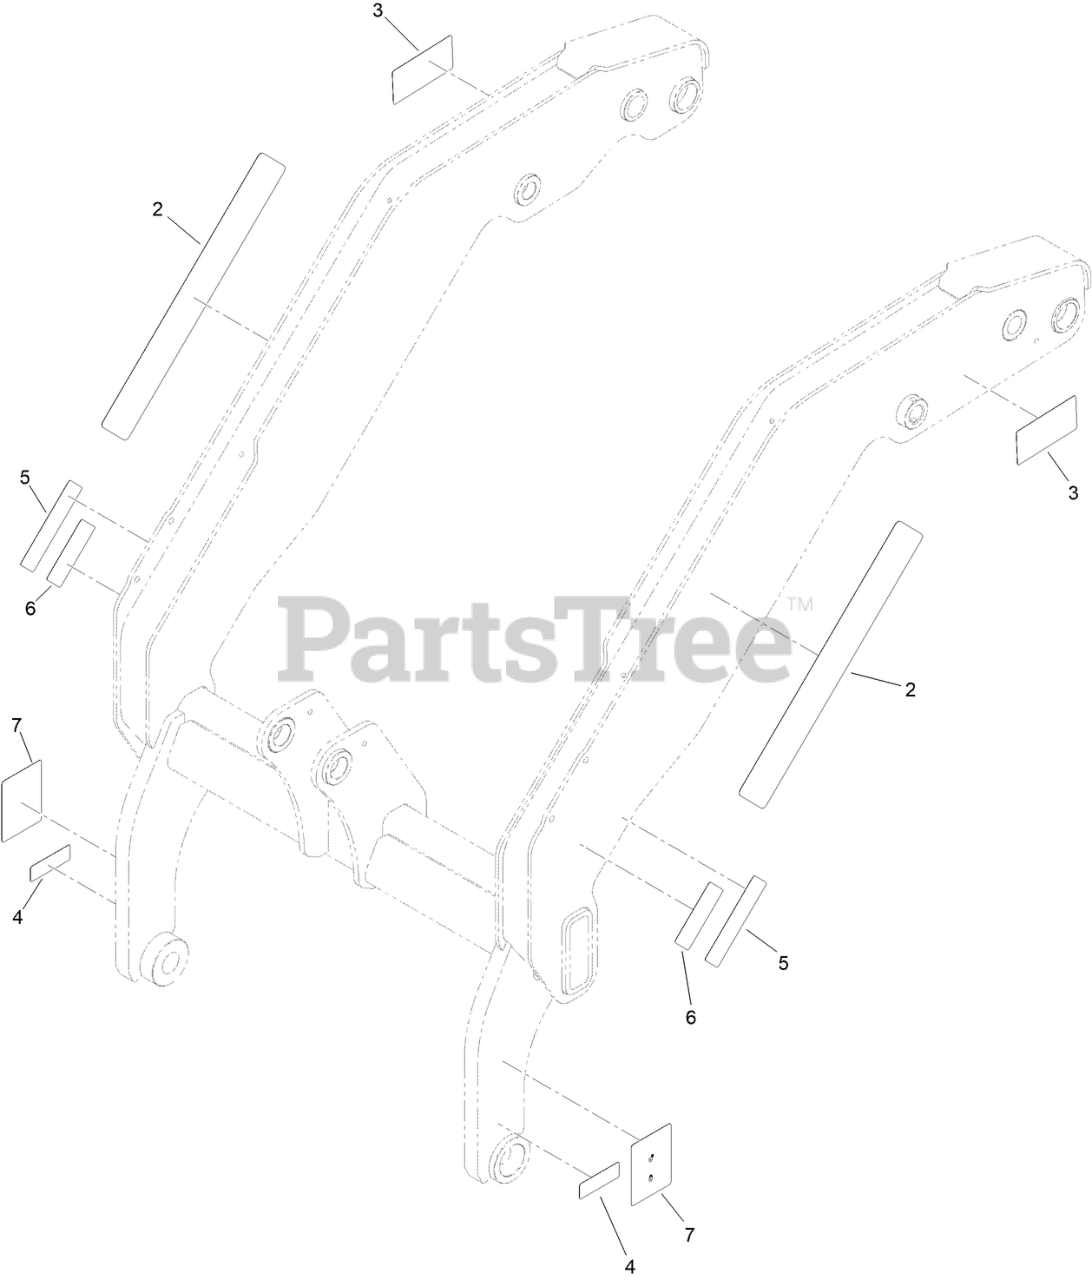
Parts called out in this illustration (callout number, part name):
2	DECAL-VERTICAL LIFT
3	DECAL-WARNING, PINCH POINT
4	DECAL-WARNING, PINCH POINT
5	DECAL-WARNING, CRUSHING
6	DECAL-WARNING, BYSTANDERS
7	DECAL - WARNING, BUCKET
